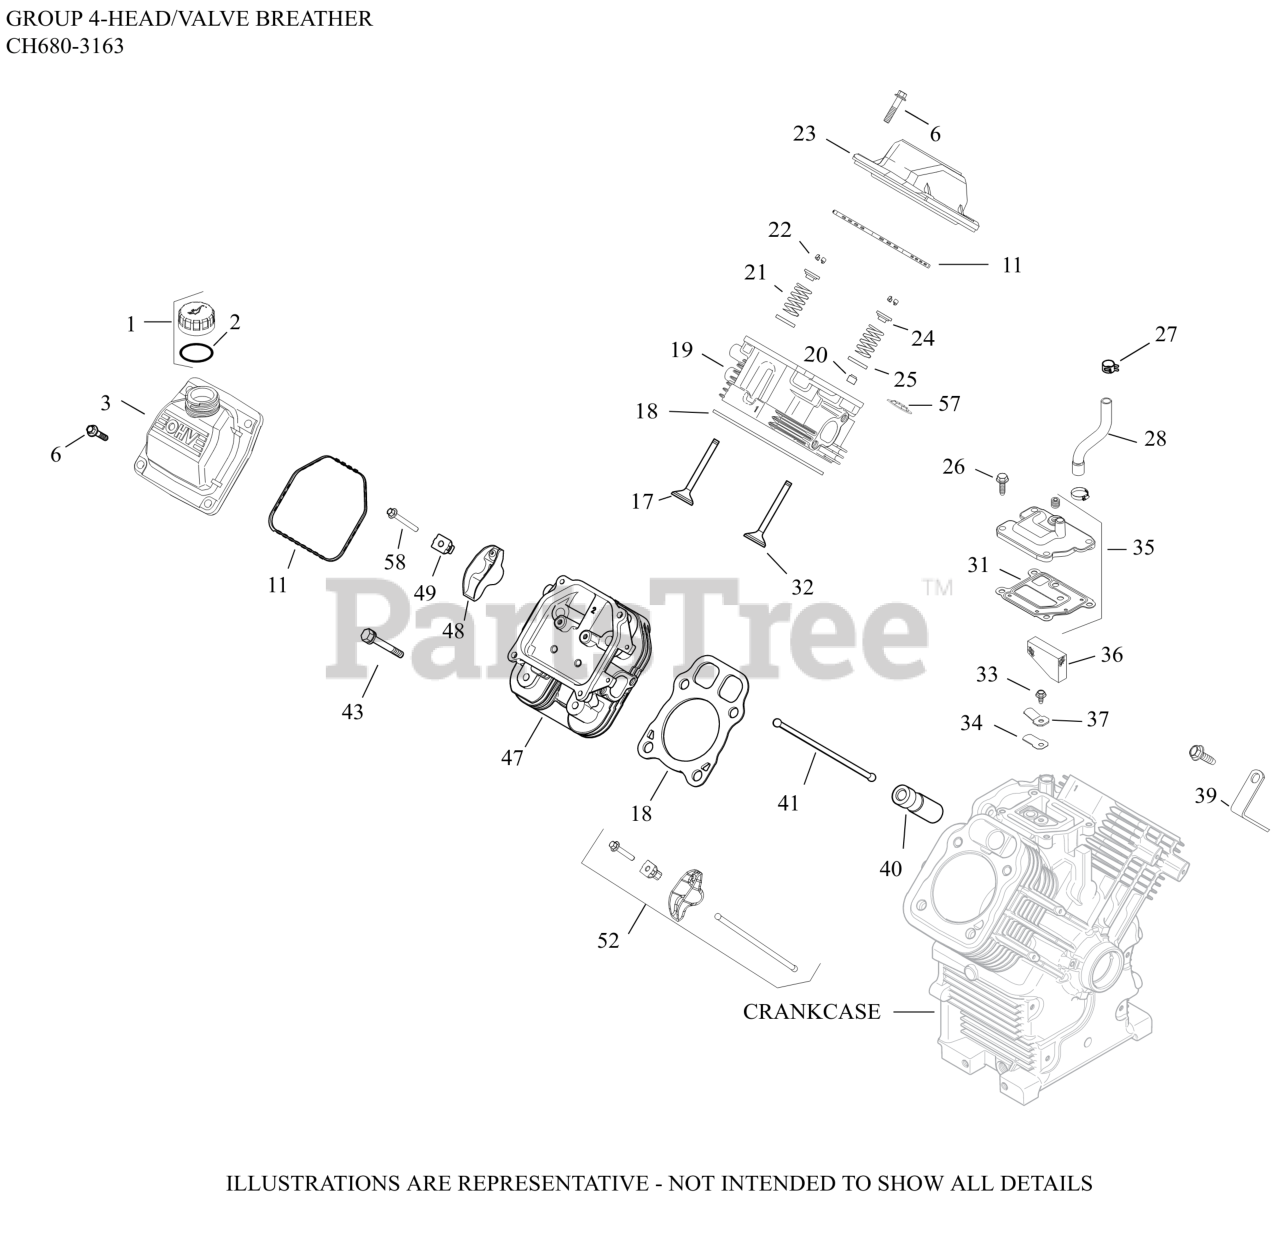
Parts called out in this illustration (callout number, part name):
1	KIT, OIL FILL CAP (YELLOW)
2	O-RING, DIPSTICK
3	KIT, VALVE COVER-OIL FILL
6	SCREW, FLG M6X1.0X30
11	O-RING (YELLOW), VALVE CO
17	VALVE, EXHAUST
17	VALVE, EXHAUST (.25)
18	KIT, GSKT CYL HD (C22-23 674CC)
19	KIT, CYLINDER HEAD (#1)-(#2481803S)
20	SEAL, VALVE BAND
21	SPRING, VALVE
22	KIT, RETAINER
23	KIT, VALVE COVER-PLAIN (PLASTIC)
24	CAP, VALVE SPRING
25	RETAINER, SPRING
26	SCREW, THREAD FORMING
27	SPRING CLAMP, HOSE
28	KIT, BREATHER HOSE AND CLAMP
31	GASKET, BREATHER
32	VALVE, INTAKE (STD)
32	VALVE, INTAKE (.25)
33	SCREW, FLG THD FRM M5X.8X10
34	REED, BREATHER
35	KIT, BREATHER ASSEMBLY
36	FILTER, BREATHER
37	RETAINER, REED
39	STRAP, LIFT
40	LIFTER, VALVE HYDRAULIC-USE 25 351 11-S
41	ROD, PUSH
43	SCREW, FLG M10X1.5X90
47	KIT, CYLINDER HEAD (#2)-(#2481804S)
48	ARM, ROCKER
49	PIVOT, ROCKER ARM
52	KIT, VALVE TRAIN
57	RETAINER, VALVE GUIDE (KM)
58	SCREW,HEX FLANGE - USE 25 086 777-S
